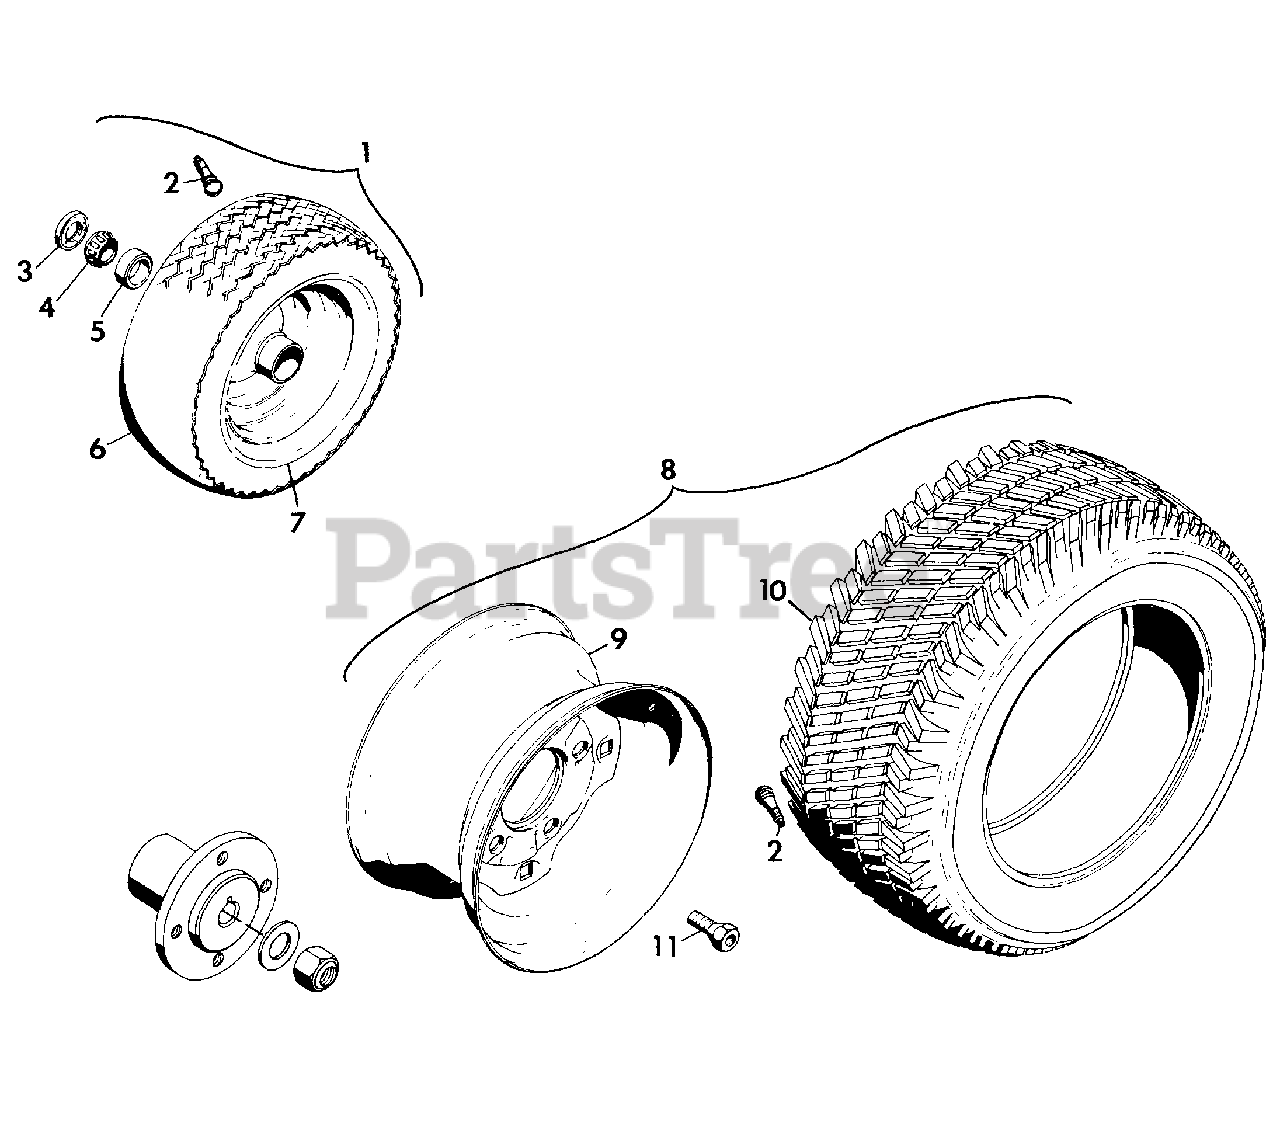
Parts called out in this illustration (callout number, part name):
1	WHEEL, REAR PRO MASTER
2	ASSEMBLY, VALVE STEM
3	SEAL, WHEEL
4	BEARING, CONE
5	BEARING, CUP
6	TIRE, 16X4.80-8
7	WHEEL
8	WHEEL, FRONT PRO MASTER
9	RIM, PRO MASTER
10	TIRE, 20X10.00-10
11	STUD, WHEEL
